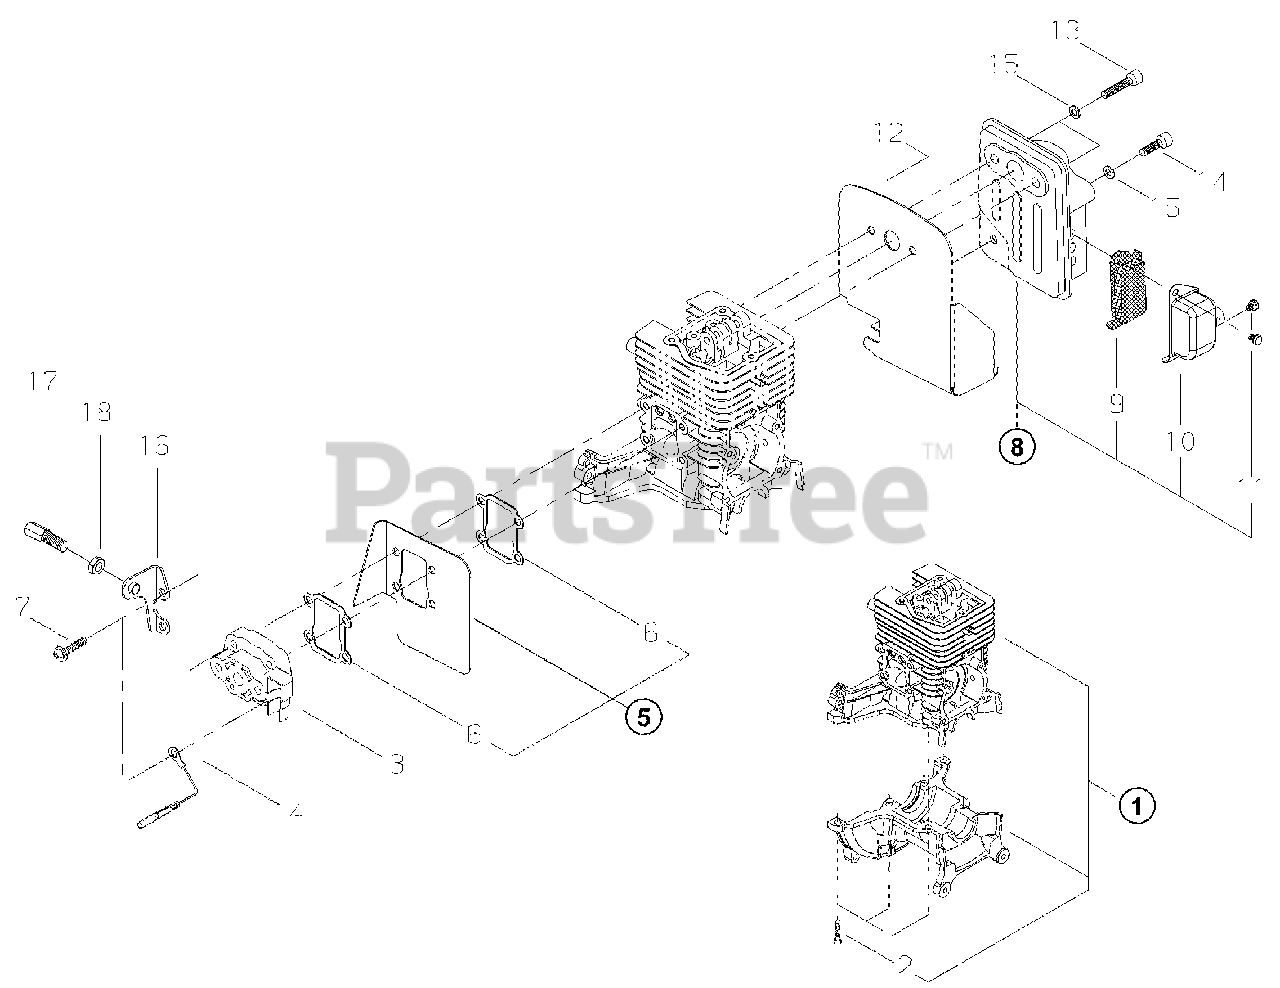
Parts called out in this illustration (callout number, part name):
1	CYLINDER BLOCK SET
2	SCREW - 5X16
3	INSULATOR
4	LEAD - GROUND
5	INTAKE SHIELD KIT
6	SHIELD, INTAKE
7	SCREW - 5X22
8	MUFFLER ASSY
9	SCREEN, SPARK ARRESTOR
10	GUIDE, EXHAUST
11	SCREW - 4X6
12	DEFLECTOR, HEAT
13	SCREW - 5X25
14	SCREW - 5X16
15	WASHER - 5
16	BRACKET, THROTTLE CABLE
17	NUT, CABLE ADJUST
18	LOCKNUT - 6
